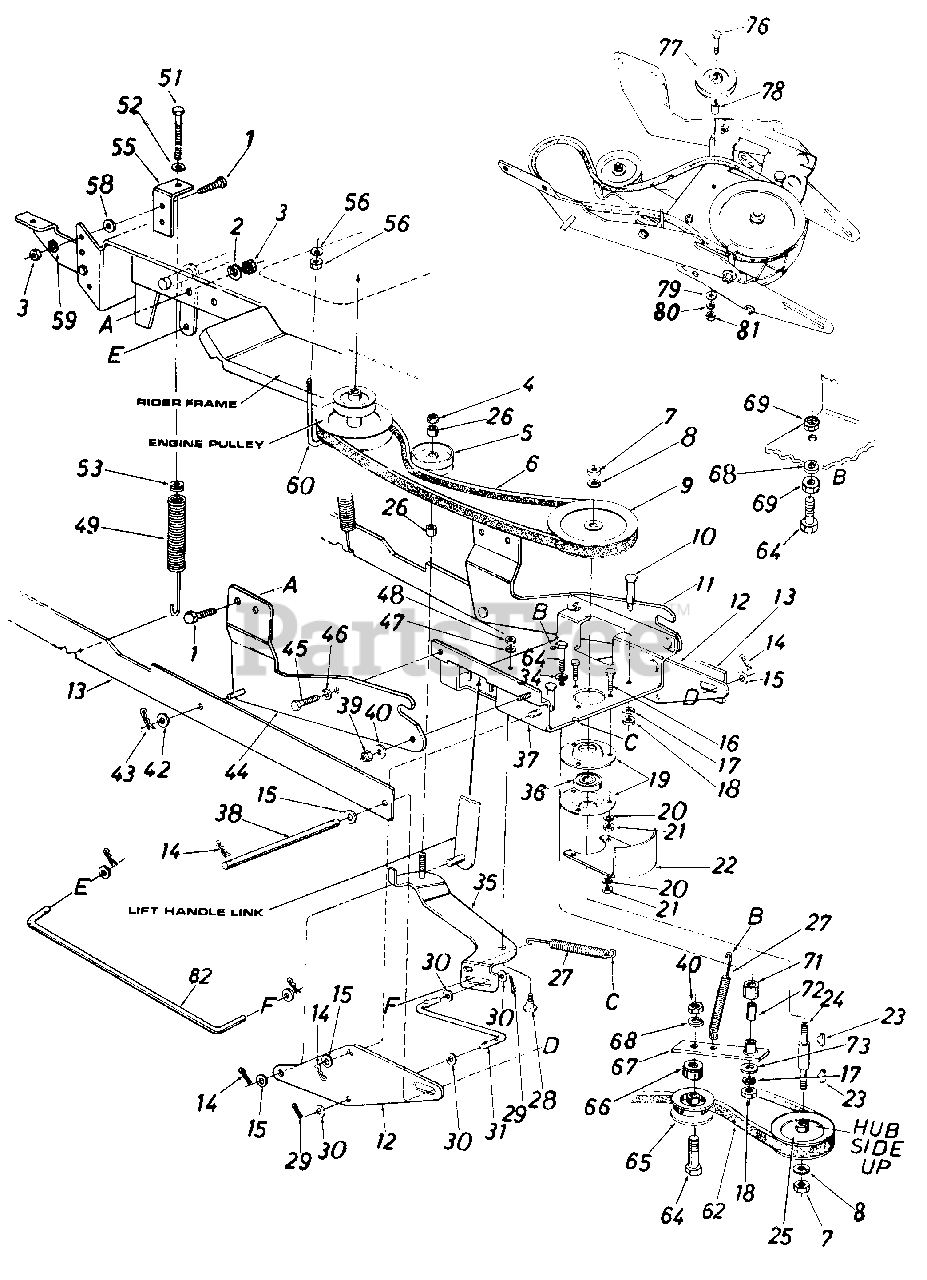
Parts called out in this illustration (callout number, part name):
1	Hex Bolt 1/4-28 x .75" Lg. Grade 5
2	L.-Wash. 1/4" I.D.*
3	Hex Nut 1/4-28 Thd.*
4	Hex Cent. L-Nut 3/8-16 Thd.
5	Idler Pulley
6	"V"-Belt 1/2 x 49" Lg.
7	Hex Jam Nut 5/8-11 Thd.
8	L-Wash. 5/8" I.D.*
9	6.50" O.D. x 5/8 Pulley
10	Shoulder Bolt
11	Channel Supporting Brkt.- R.H.
12	Linkage Brkt.
13	Linkage Arm Ass'y.
14	Intern. Cotter Pin .50 Dia.*
15	Fl.-Wash.
16	Hex Bolt 5/16 x 1.25" Lg.
17	L.-Wash. 3/8" I.D.*
18	Hex Jam Nut 3/8-16 Thd.
19	Bearing Housing
20	L.-Wash. 5/16" I.D.*
21	Hex Nut 5/16-18 Thd.*
24	Pulley Spindle
25	5/8 Pulley-6.28 I.D. x 5.56 O.D.
26	Spacer .383 I.D. x .503 O.D. x .562 Lg.
27	Extension Spring .54 O.D. x 5.25"
28	Shoulder Bolt
29	Cotter Pin 3/32" Dia. x 1.C
30	Fl.-Wash.
31	Control Rod
34	Hex Sems Scr. 5/16-18 x 1.0" Lg.*
35	Clutch Idler Brkt. Ass'y.
36	Ball Bearing
37	Channel Ass'y.
38	Lift Handle Shaft
39	Hex Jam Nut 3/8-16 Thd.
40	L.-Wash. 3/8" I.D.*
42	Fl.-Wash.
43	Intern. Cotter Pin .50" Dia.*
44	Channel Supporting Brkt.- L.H.
45	Hex Bolt 3/8-16 x x 1.0" Lg.*
46	L.-Wash. 3/8" I.D.*
47	L.Wash.5/16" I.D.*
48	Hex Nut 5/16-18 Thd.*
49	Helper Spring
51	Hex Scr. 5/16-18 x 2.0" Lg. [Special
52	Bell Wash. .345 I.D. x .88 O.D. x .06
53	Spring Insert
58	Fl.-Wash. .264" I.D.
59	L.-Wash. 1/4" I.D.*
60	J-Bolt 5/16-18 Thd.
62	"V"-Belt 1/2 "A" x .89" Lg.
64	Hex Bolt 3/8-16 x 2.0" Lg.*
65	Idler Pulley
66	Spacer .385 I.D. x .503 O.D. x.562" Lg.
67	Idler Arm Ass'y.
68	L.-Wash. 3/8" I.D.*
69	Hex Jam Nut 3/8-16 Thd.
71	Hex Bolt 5/16-19 x 1-1/4"
72	Spacer .3775 I.D. x .60 O.D. x 8.3 Lg.
73	Fl.-Wash. 3/8 I.D. x 1" O.D. x 1.27
76	Hex Bolt 3/8-16 x 2.5" Lg. (Grade 5)
77	Idler Pulley .38 I.D. x 3.06 O.D.
78	Spacer .385 I.D. x .630 O.D. x .76 Lg. I
79	Fl.-Wash. .39 I.D. x 1-3/4 O.D. x 3/16
80	L-Wash. 3/8" I.D.*
81	Hex Nut 3/8-16 Thd.*
82	Clutch Control Rod 13.67" Lg.
